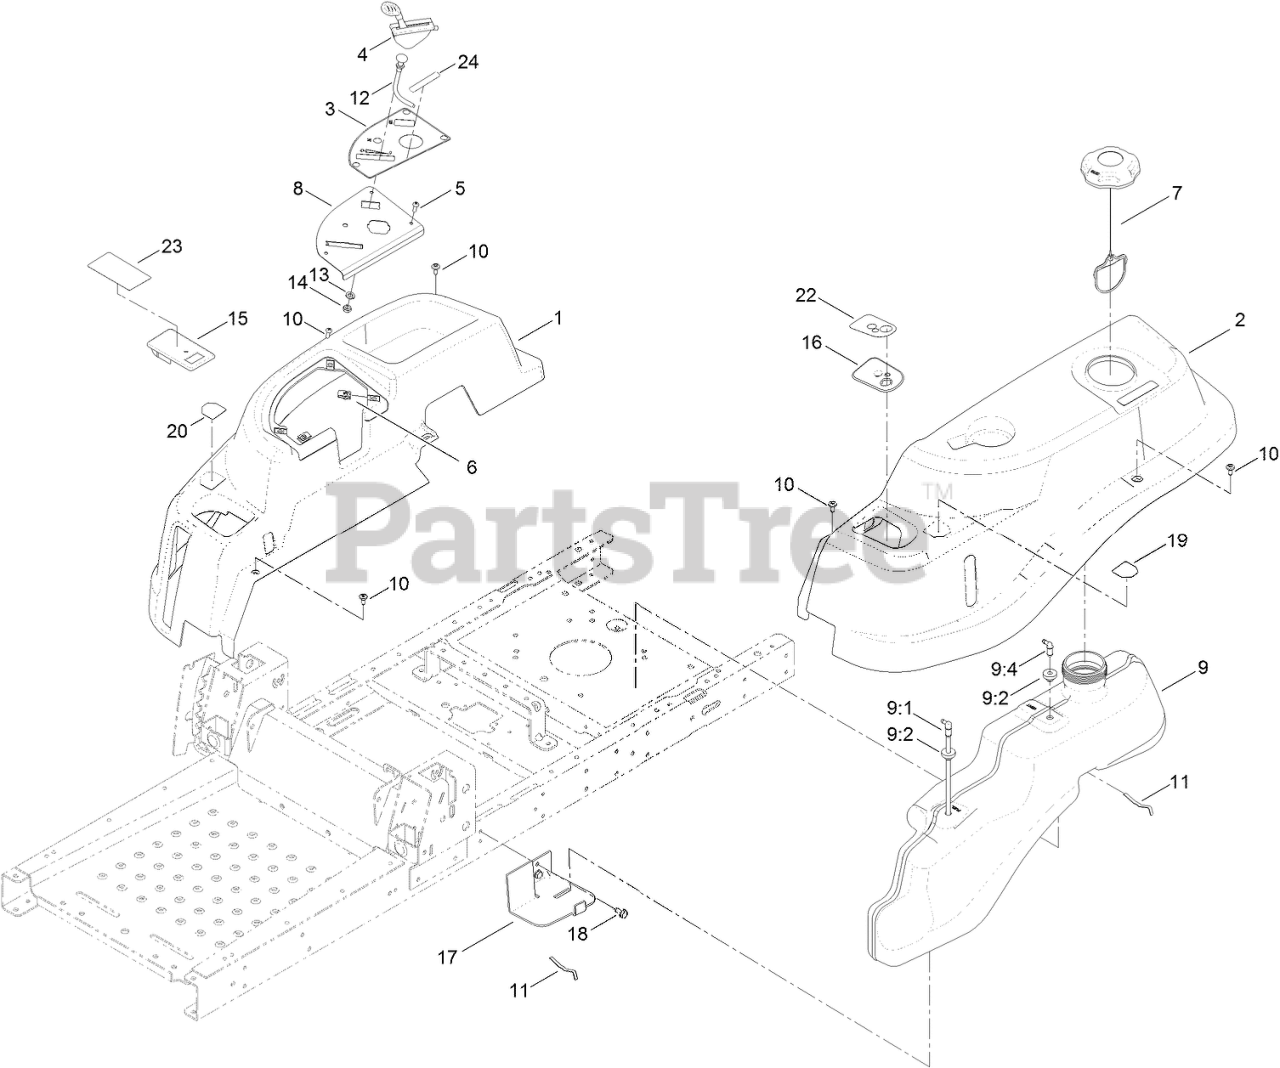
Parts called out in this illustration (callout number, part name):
1	POD-RH
2	POD-LH
3	DECAL-PANEL, CONTROL
4	CABLE-THROTTLE
5	SCREW-PRH
7	CAP-FUEL, RATCHETING
8	PLATE-CONTROL
9	FUEL TANK ASM
9:1	CONNECTOR-ELBOW, 90 DEG
9:2	BUSHING
9:4	FITTING-PLASTIC
10	SCREW-SHOULDER
11	SPRING
12	CABLE-CHOKE
13	WASHER-LOCK
14	NUT-HJ
15	COVER-RH
16	COVER-LH
17	SUPPORT-TANK, FRONT
18	SCREW-HWHTF
19	DECAL-NMIR
20	DECAL-CONTROL, PEDAL
22	DECAL-KEYCHOICE
23	DECAL-BRAKE, PARKING
24	DECAL-SHUTDOWN
